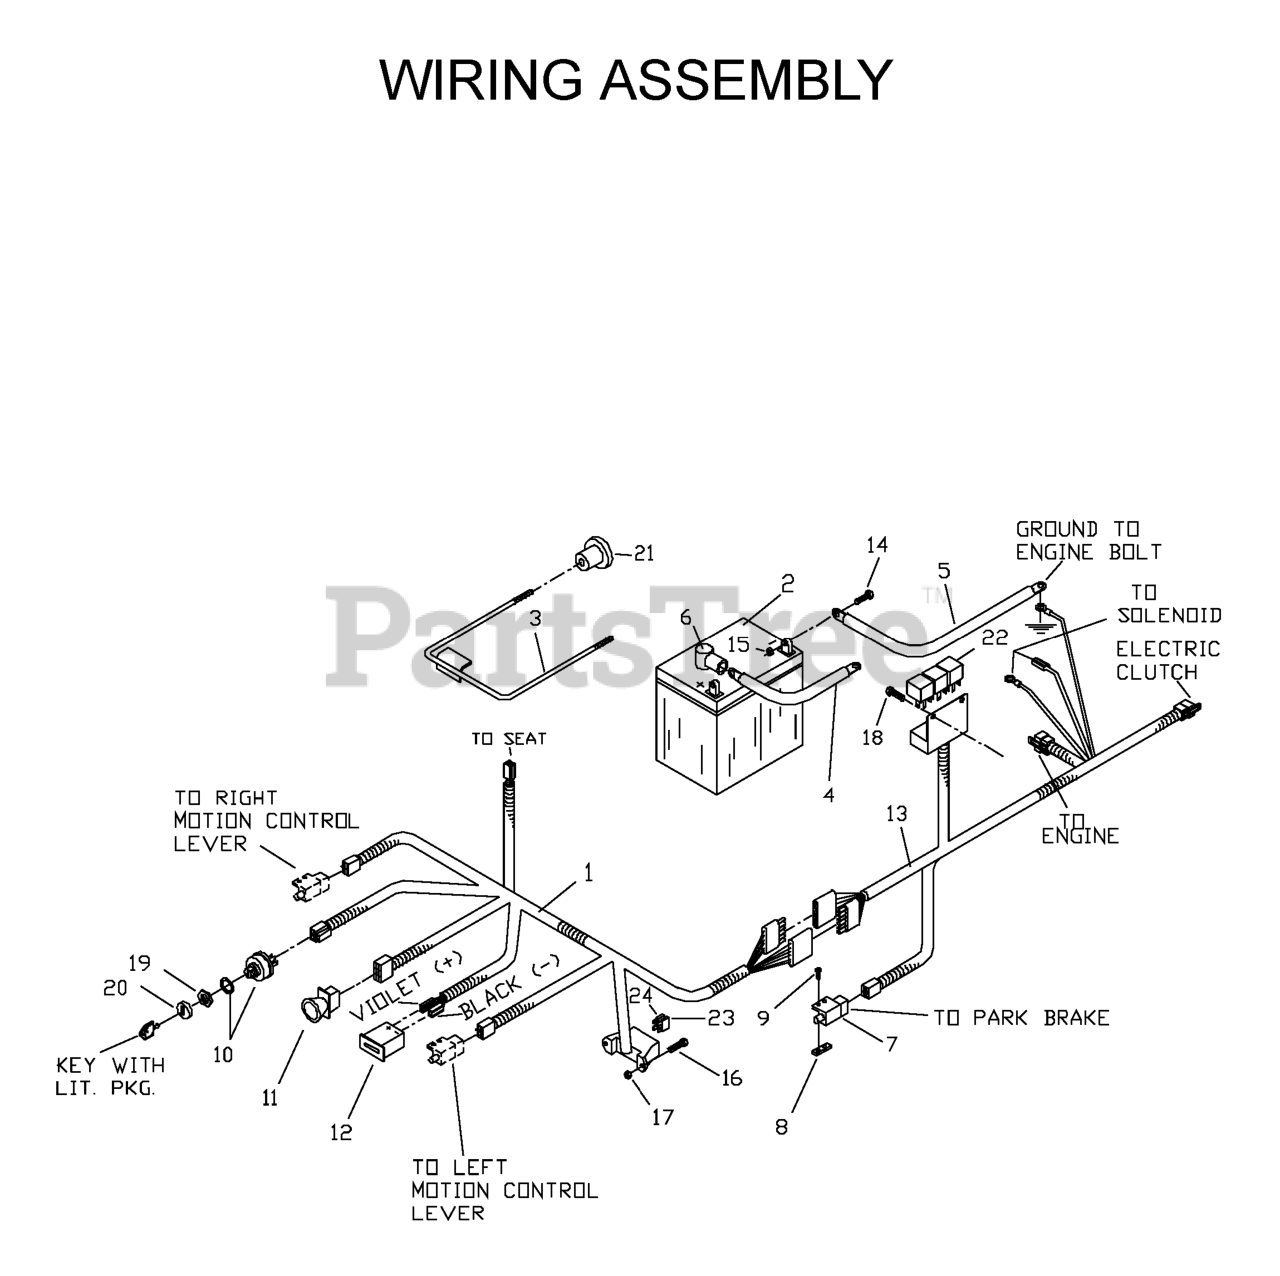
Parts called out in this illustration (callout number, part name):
1	CONSOLE HARNESS
2	BATTERY WET NOT SELLABLE
3	BATTERY HOLD DOWN
4	POST.CABLE LONG
5	CABLE-NEGATIVE
7	SWITCH, INTERLOCK
8	TAPPED PLATE
9	SCREW #10-24 X 5/8
10	IGNITION SWITCH KIT
11	RP.SWITCH, BLADE
12	HOUR METER
13	FRAMES HARNESS
14	HCS 5/16C X 3/4
15	NUT 5/16C CENTERLOCK
16	SCREW, #1--24 X 1/2 SLOTTED
17	NUT 10-24 NYLOC
18	SCREW #10 X 1/2 SELF TAPPING
19	DNO IGNITION NUT
20	CAP IGNITION NUT
23	FUSE, 7.5 AMP 32 VOLT ATO
24	FUSE, 20 AMP 32 VOLT ATO
